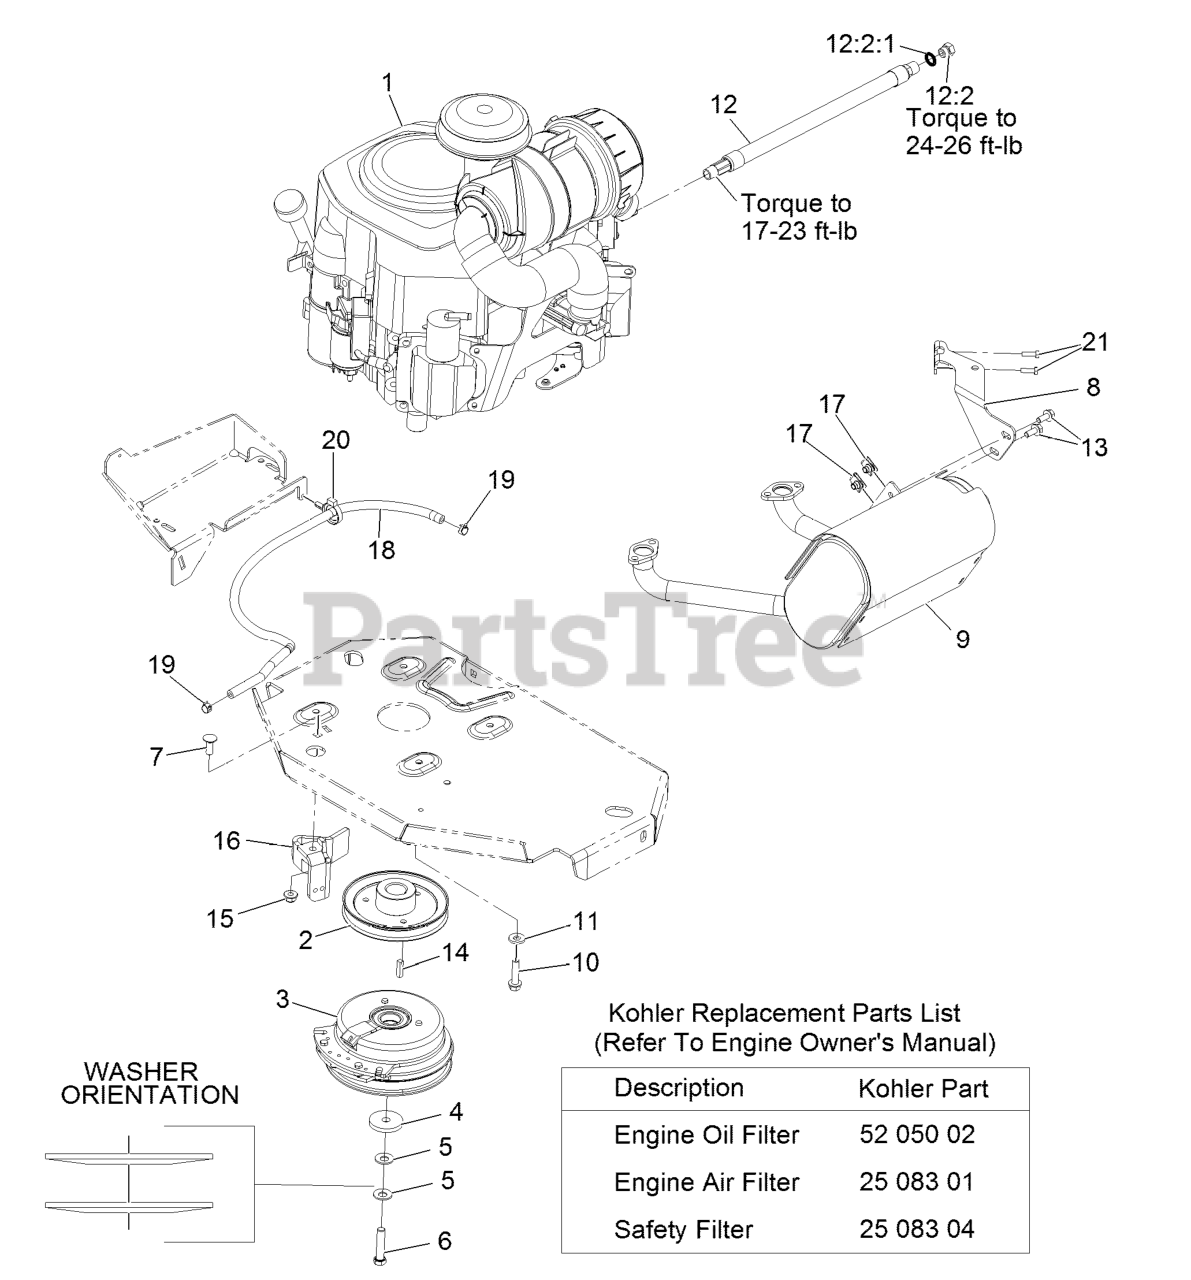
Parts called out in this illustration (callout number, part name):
1	Engine-Kohler
2	SHEAVE
3	CLUTCH KIT
4	WASHER-CLUTCH
5	WASHER-SPRING
6	SCREW-HH W/LOCTITE
7	SCREW-CARR
8	MUFFLER BRACKET KIT
10	SCREW-HWH
11	WASHER-BELLEVILLE
12	OIL DRAIN HOSE ASM
12:2	PLUG-HH
12:2:1	O-RING
13	SCREW-HHF
15	NUT-HF, NI
16	CLUTCH-ANCHOR
18	HOSE-FUEL
19	CLAMP-HOSE
20	CLAMP-HOSE
21	SCREW-HH M6-1 X 20Mm W/Patch
